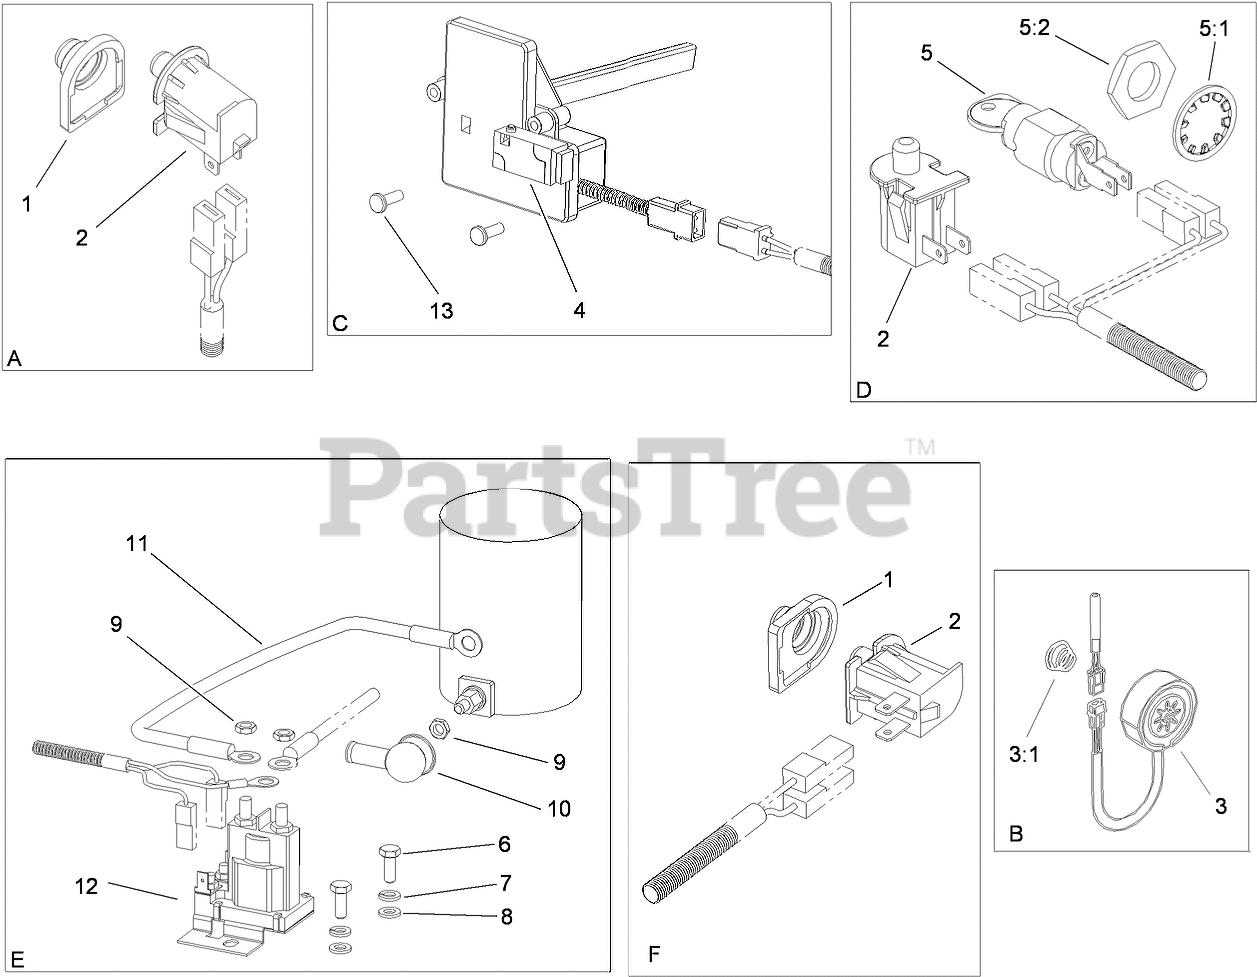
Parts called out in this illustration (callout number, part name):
1	COVER-PROTECTIVE
2	SWITCH-DELTA
3	MAGNET ASM
3:1	SPRING-COMPRESSION
4	OVERLOAD SWITCH ASM
5	STARTER SWITCH ASM
5:1	WASHER-TOOTH, INTERNAL
5:2	NUT-HH
6	SCREW-HH
7	WASHER-SPRING
8	WASHER-FLAT
9	NUT-HHF
10	BOOT-RUBBER
11	LEAD-STARTER, ELECTRIC
12	Solenoid
13	Screw
